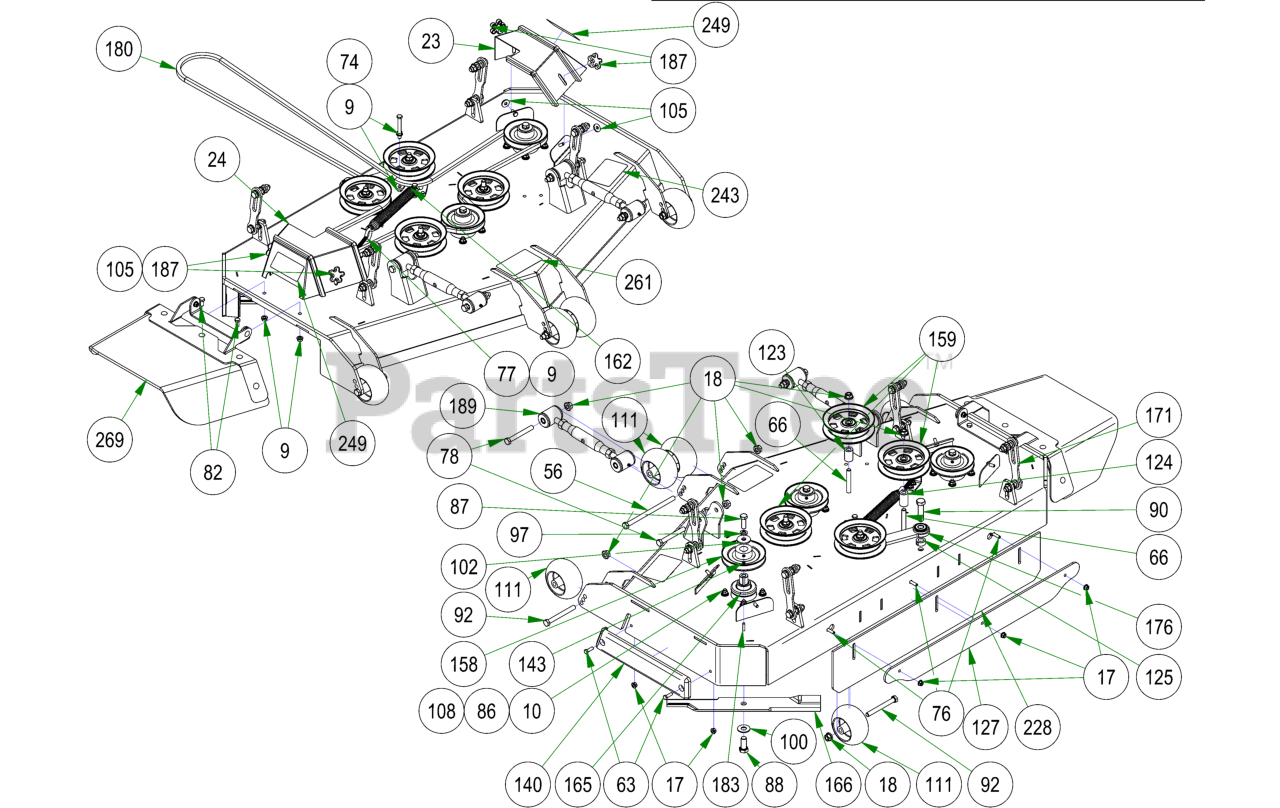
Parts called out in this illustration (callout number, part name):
9	3/8-16 HEX SERRATED FLANGE NUT HARD/ZINC
10	3/8-16 NYLON INSERT FLANGE LOCKNUT (GR.F) ZINC
12	3/8-16 HEX NUT ZINC
15	5/8-11 NYLON INSERT LOCKNUT ZINC
17	5/16-18 NYLON INSERT FLANGE LOCKNUT ZINC
18	1/2-13 NYLON INSERT FLANGE LOCKNUT ZINC
23	2019 54" Left Outlaw Gen2 Pulley Cover
24	2019 54" Right Outlaw Gen2 Pulley Cover
56	1/2-13 X 8 HEX CAP SCREW GR 5 ZINC
63	5/16-18 X 1 HEX CAP SCREW (GR.5) ZINC
66	1/2-13 X 3-1/2 HEX FLANGE BOLT (GR.8) ZINC
74	3/8-16 X 3 HEX CAP SCREW (GR.5) ZINC
76	5/16-18 X 1-1/4 CARRIAGE BOLT ZINC
77	4" 3/8-16 Eye Bolt
78	1/2-13 X 4 HEX CAP SCREW (GR.8) ZINC YELLOW
82	3/8-16 X 3/4 HEX CAP SCREW (GR.5) ZINC
86	3/8-16 X 1-1/2 HEX CAP SCREW (GR.5) ZINC
87	1/2-20 X 1-1/2 HEX CAP SCREW (GR.5) ZINC
88	5/8-18 X 1-1/2 HEX CAP SCREW (GR.8) ZINC YELLOW
90	5/8-11 X 2-1/2 HEX CAP SCREW (GR.5) ZINC
92	1/2-13 X 4-1/2 HEX CAP SCREW (GR.5) ZINC
95	5/16-18 X 7/8 CARRIAGE BOLT ZINC
97	1/2 SPLIT LOCKWASHER (GR.8) ZINC/YELLOW
100	5/8 USS FLAT WASHER (1-3/4" OD) GR.8 ZINC YELLOW
102	1/2 BELLEVILLE WASHER (1-5/8 OD X .140 THK) ZINC
105	.360 ID X .983 OD X .120 THICK FLAT WASHER NYLON BLACK
108	5/16 USS FLAT WASHER (7/8 OD) ZINC
111	2019 Deck Wheel
123	.502 ID X .750 OD X 1.500 Long Spacer
124	1 3/4" Pulley Spacer
125	5/8 SOLID SHAFT COLLAR (W/1 SET SCREW) ZINC
127	61 Bolt in Baffle Deck v2 Stripping Plate
140	REVISED TRIM BUMPER_20180226
143	5/16-24 X 1/4 SOCKET SET SCREW (CUP PT) PLAIN
158	5.25" Deck Spindle Pulley
159	5-3/4 Idler Pulley
162	2019 Outlaw Gen2 Deck Spring
165	OUTLAW SPINDLE ASSEMBLY
166	54" Fusion Blade for ZT/Mav/Outlaw/Revolt
169	2019 Deck Eye Bolt Tab
171	Deck Hangar Assembly
176	2019 Rebel Rogue Deck Idler
180	B165 Belt-60 54" deck Outlaw
183	1/4 X 1 SQ MACHINERY KEY 1018 STL PLN
187	5/16" Knob
189	Turnbuckle
204	2019 Sloped 54" Deck
228	R Series Rubber For Deck
243	2018 54" Deck Decal
249	Danger Decal-Spindle/Discharge
261	2019 Rebel & Rogue Deck Belt Route Decal
269	2019 Outlaw Gen2 Chute Assembly
